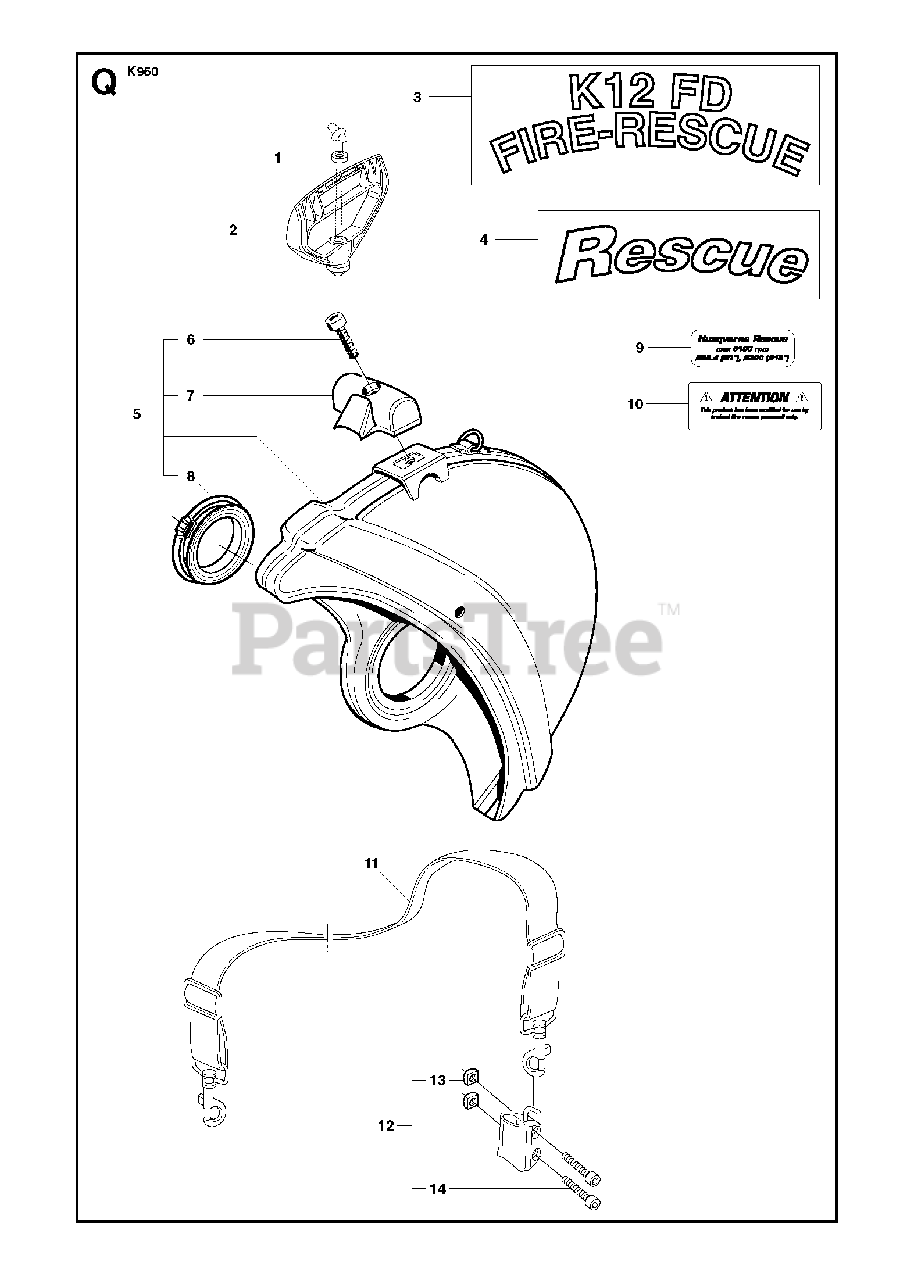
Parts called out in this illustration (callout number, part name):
2	STARTER HANDLE
5	WHEEL GUARD ASSY"Rescue 14"". Incl. 6 - 8"
5	WHEEL GUARD"Rescue 12"". Incl. 6 - 8"
6	SCREW IHSCM
11	SHOULDER STRAP
12	BRACKETIncl. 13, 14
14	SCREW ITXSCM
